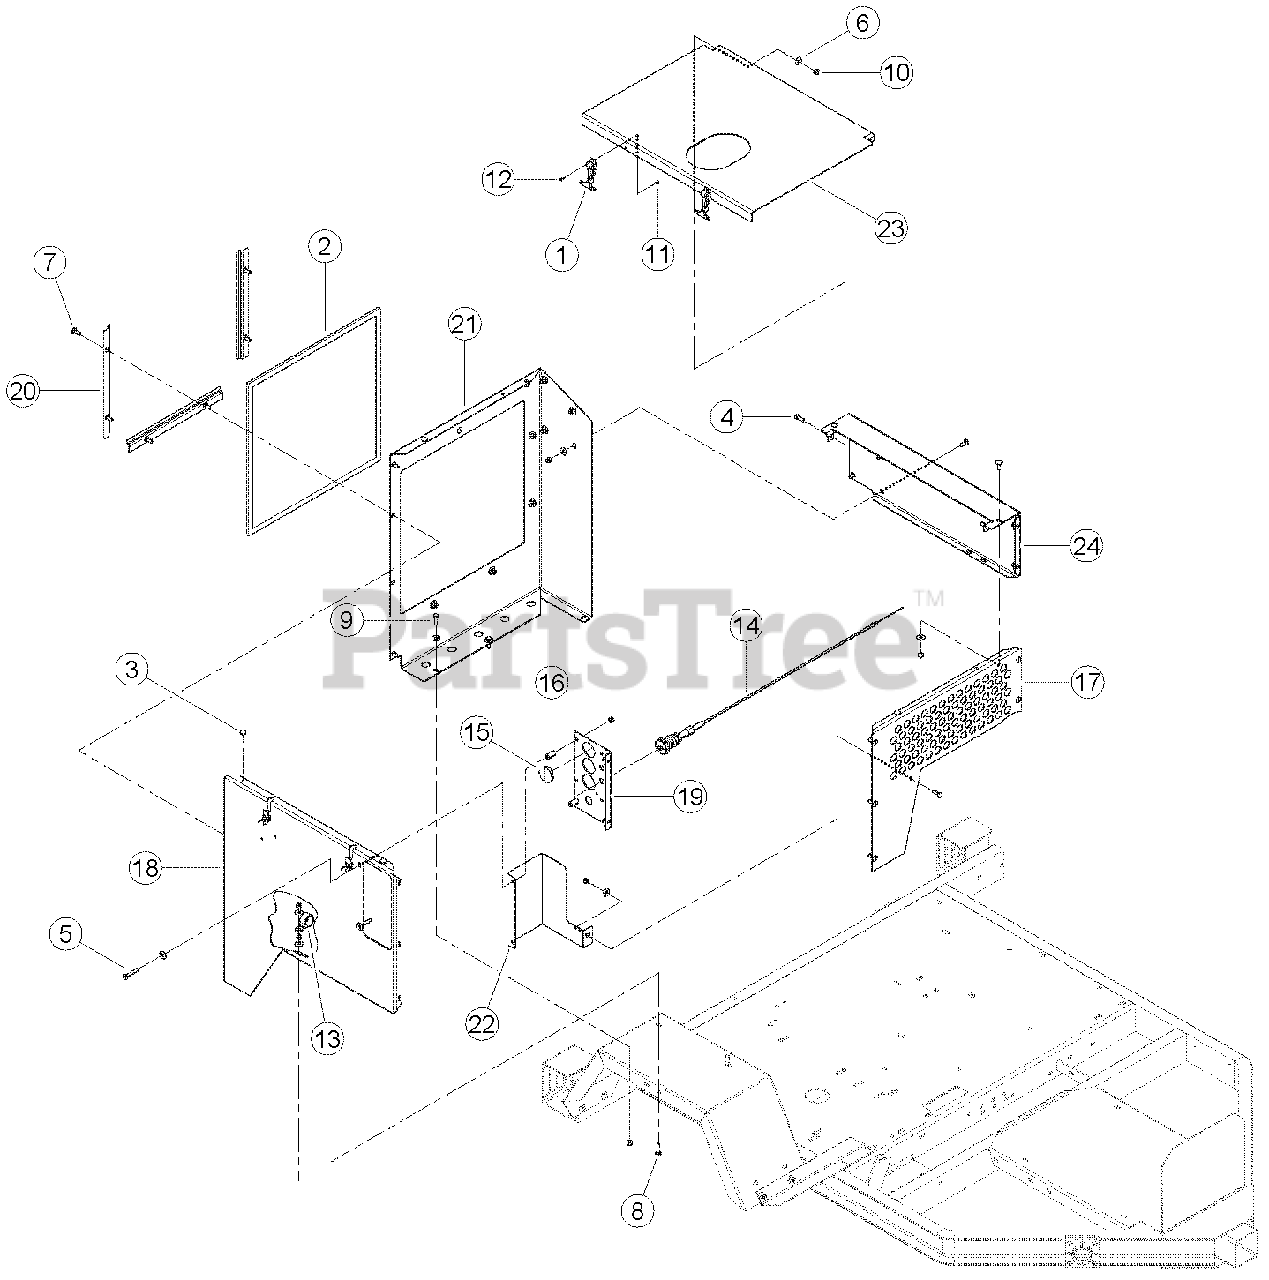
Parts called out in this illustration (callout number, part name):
1	LATCH, FLEXIBLE DRAW (2-PIECE)
2	SCREEN, RADIATOR INLET
3	BUMPER, RUBBER
4	BOLT, 3/8 X 1 HEX HD GR5 ZP
5	BOLT, 3/8 X 2 HEX HD GR5 ZP
6	WASHER, 3/8 FLAT ZP
7	BOLT, 3/8 X 1 CRG GR5 NC ZP
8	BOLT, 3/8 X 1-1/2 CRG GR5 NC ZP
9	BOLT, 3/8 X 1-1/4 HEX HD GR5 ZP
10	NUT, 3/8 NE NYLOCK ZP
11	NUT, 10/24 NYLOCK TYPE NM ZP
12	SCREW, MCH 10-24 X 1/2 PAN HD PH ZP
13	CLAMP, 1-9/16 COATED METAL
14	CABLE, DIESEL THROTTLE
15	PLUG, 2 IN. DOME
16	IDLER SPACER
17	COVER, REAR ENGINE
18	PANEL, SIDE COVER
19	PANEL, ENGINE CONTROL
20	BRACKET, SCREEN HOLDER
21	PANEL, RADIATOR COVER
22	SHIELD, 50 HP HEAT
23	HOOD, ENGINE
24	SIDE, ENGINE COVER
